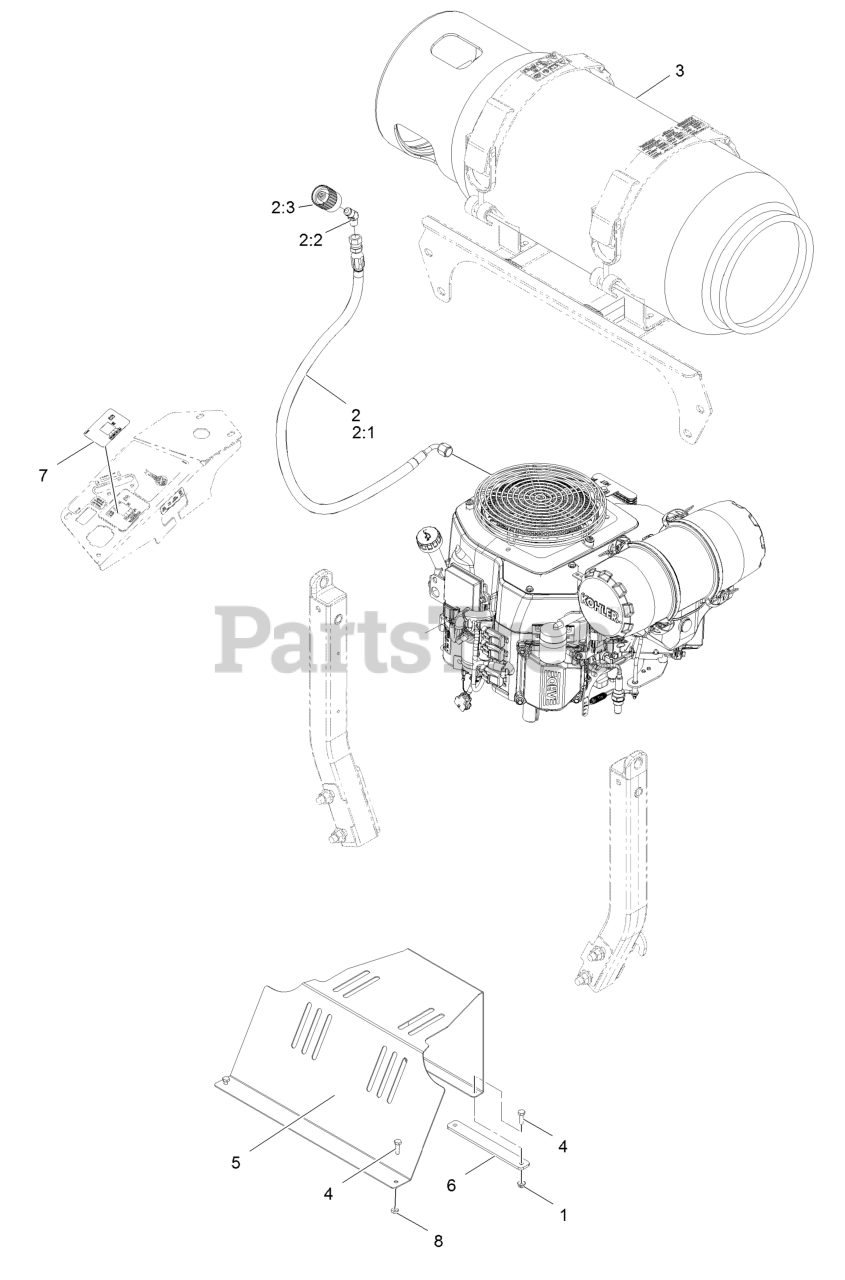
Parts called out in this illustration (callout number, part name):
2:1	LPG FUEL HOSE ASM
2:2	ELBOW-45 DEG
2:3	CONNECTOR-LPG TANK, LH TH
4	SCREW-HH
5	SHEILD-FAN
7	DECAL-METER, HOUR
8	NUT-JAM
